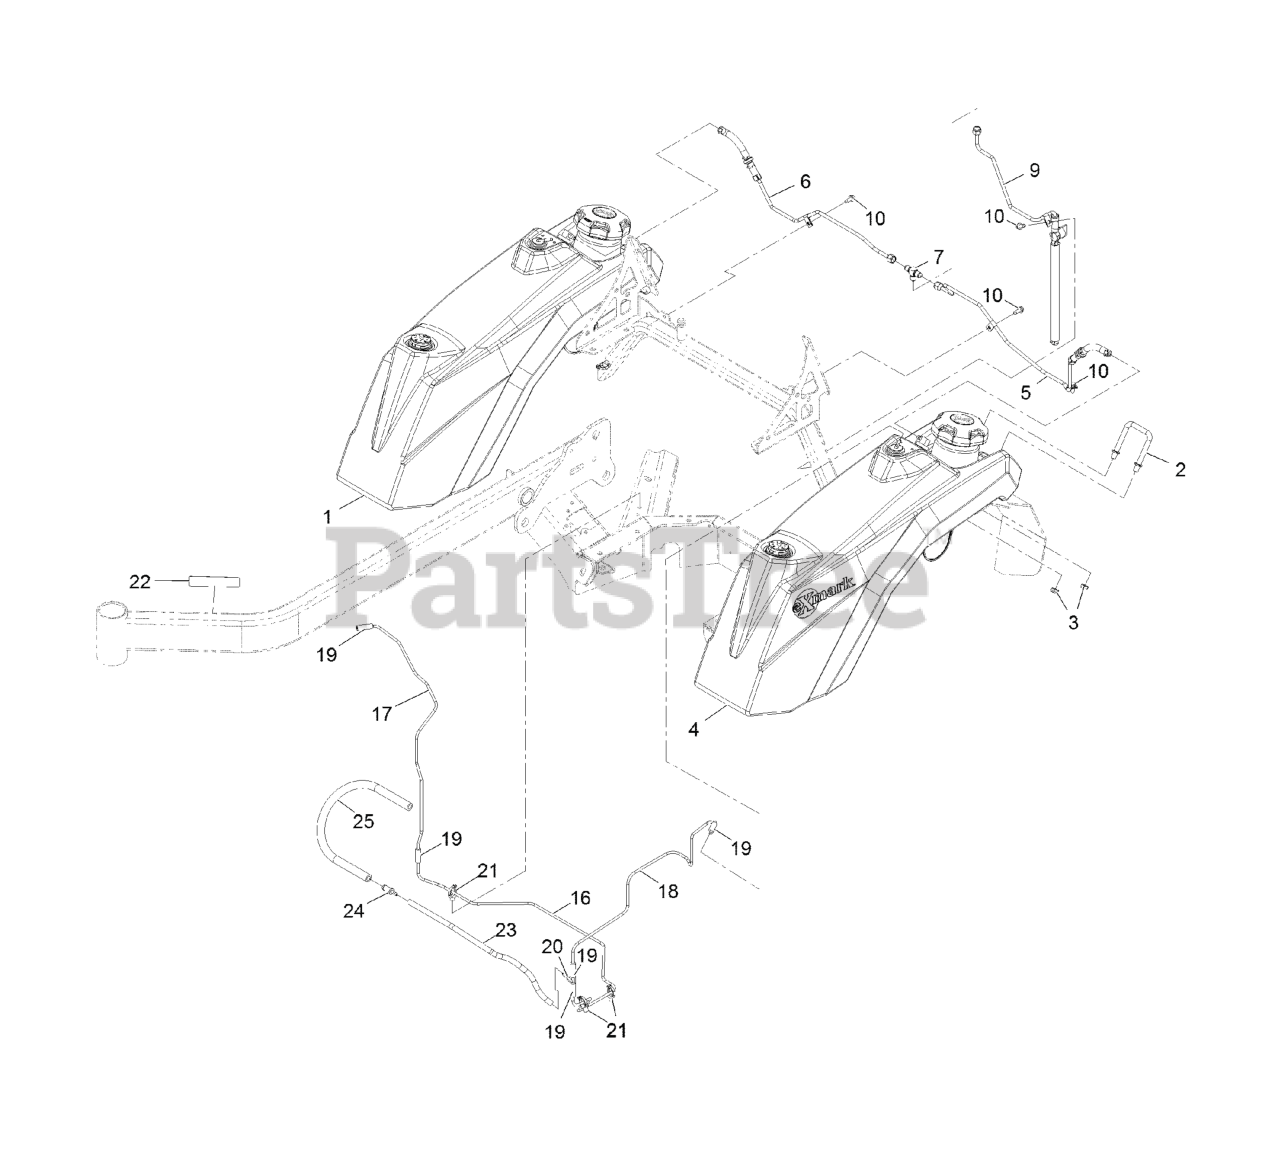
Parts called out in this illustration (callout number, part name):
1	ASM, RT FUEL TANK
2	CLAMP, TANK
4	ASM, LT FUEL TANK
6	X-REF 142-3598
7	FITTING, 2603-4-4-4
10	SCREW-HWH
16	LINE, VENT, MAIN
17	LINE, VENT, RIGHT
18	LINE, VENT, LEFT
19	HOSE-FUEL
20	FITTING, 3/16" Y
21	CLIP-TIE
22	DECAL-ARRESTOR, SPARK
23	HOSE, VENT
24	FITTING-STRAIGHT
25	HOSE-FUEL
